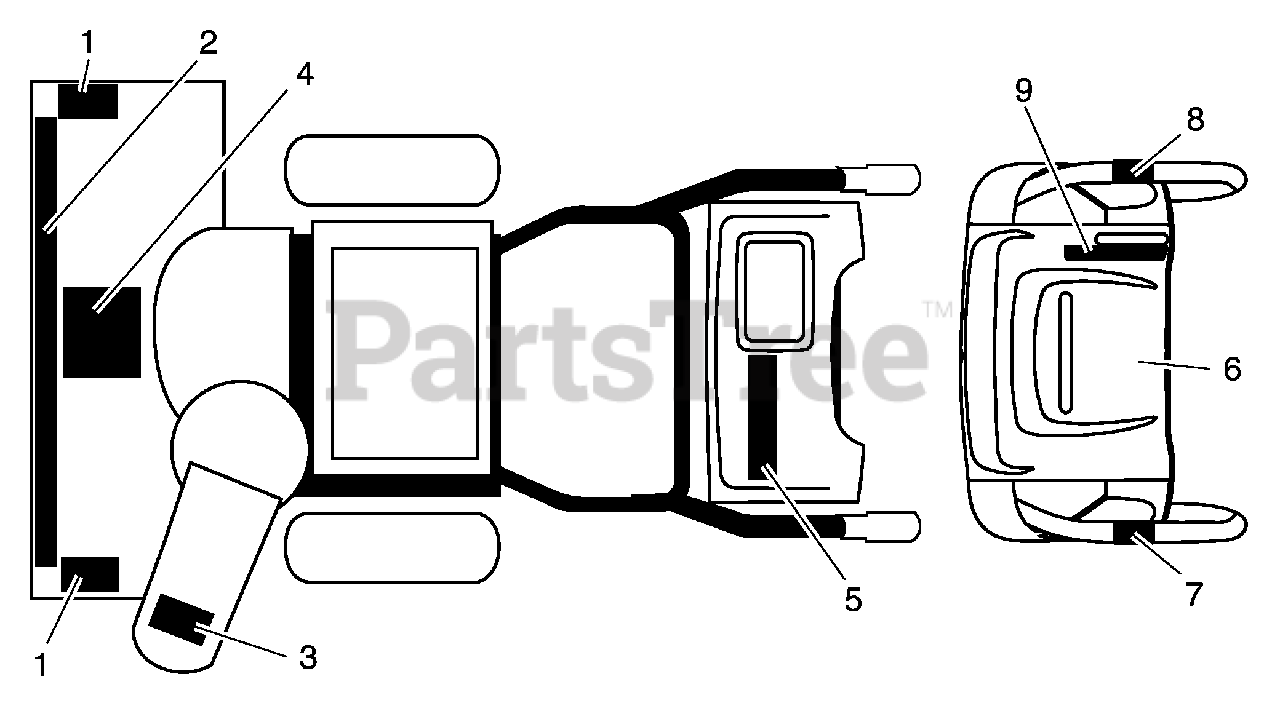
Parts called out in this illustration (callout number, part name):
1	Decal, Danger
2	Decal, Poulan Pro, 5 HP / 24" (large)
3	Decal, Danger, Deflector
4	Decal, Danger
5	Decal, Poulan Pro, 5 HP / 24" (small)
6	Decal, Instruction
7	Decal, Traction Lever
8	Decal, Auger Lever
9	Decal, Speed Control
